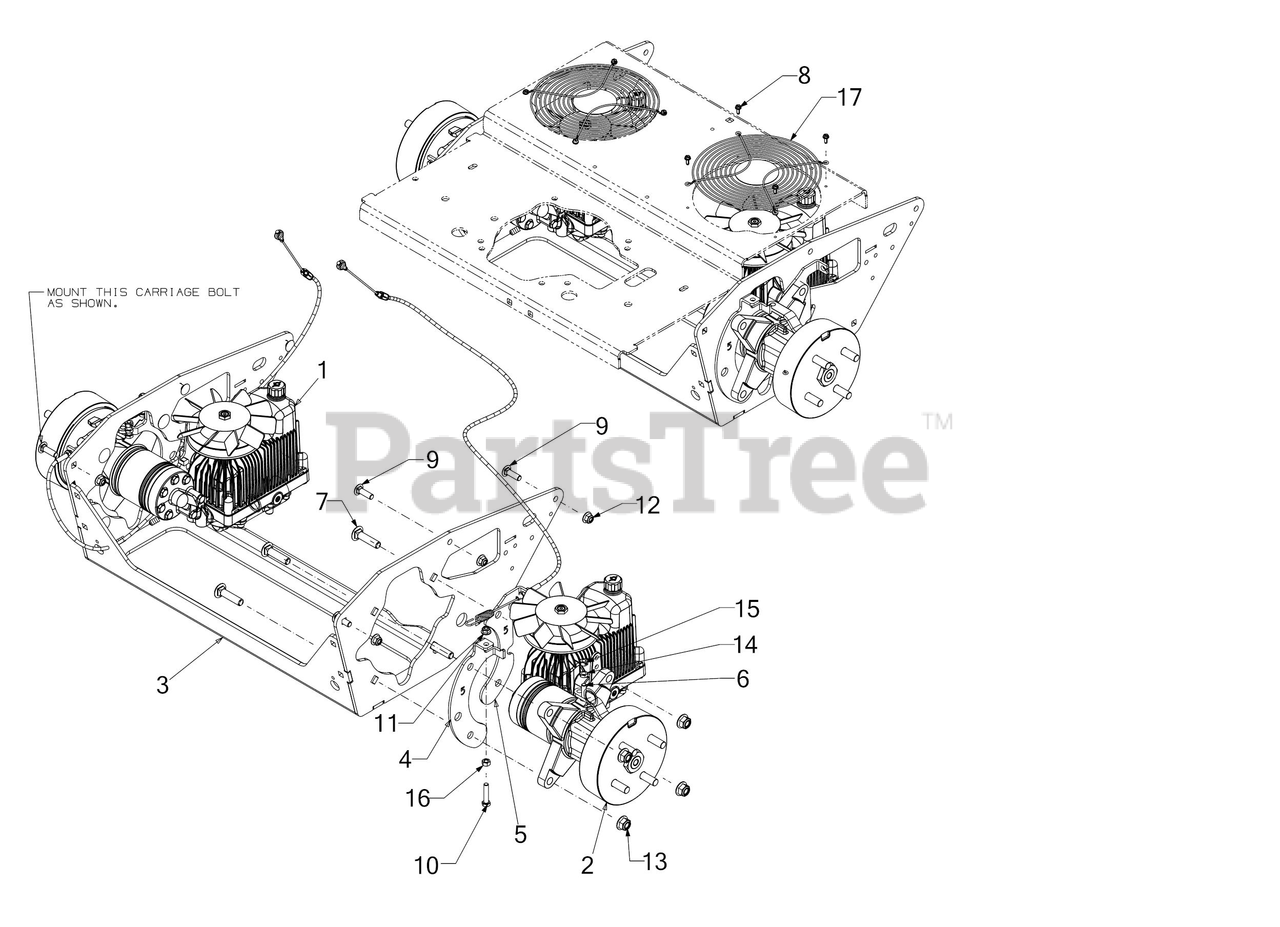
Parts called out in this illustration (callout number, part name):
1	TRANSMISSION / MOTOR ASSEMBLY (LH)
2	TRANSMISSION / MOTOR ASSEMBLY (RH)
3	TRANSMISSION MOUNTING BRACKET ASSEMBLY
4	SPRING BRAKE MOUNTING BRACKET
5	BRAKE CABLE BRACKET
6	SCREW 5/16-18 x 1.0 GR5
7	CARRIAGE BOLT 1/2-13 GR5
8	SCREW 10-24 x 0.500
9	CARRIAGE BOLT 3/8-16 X1.25 GR5
10	SCREW 5/16-18 x 1.5 LG
11	FLANGE LOCK NUT 5/16-18
15	HEX NUT
16	HEX NUT
